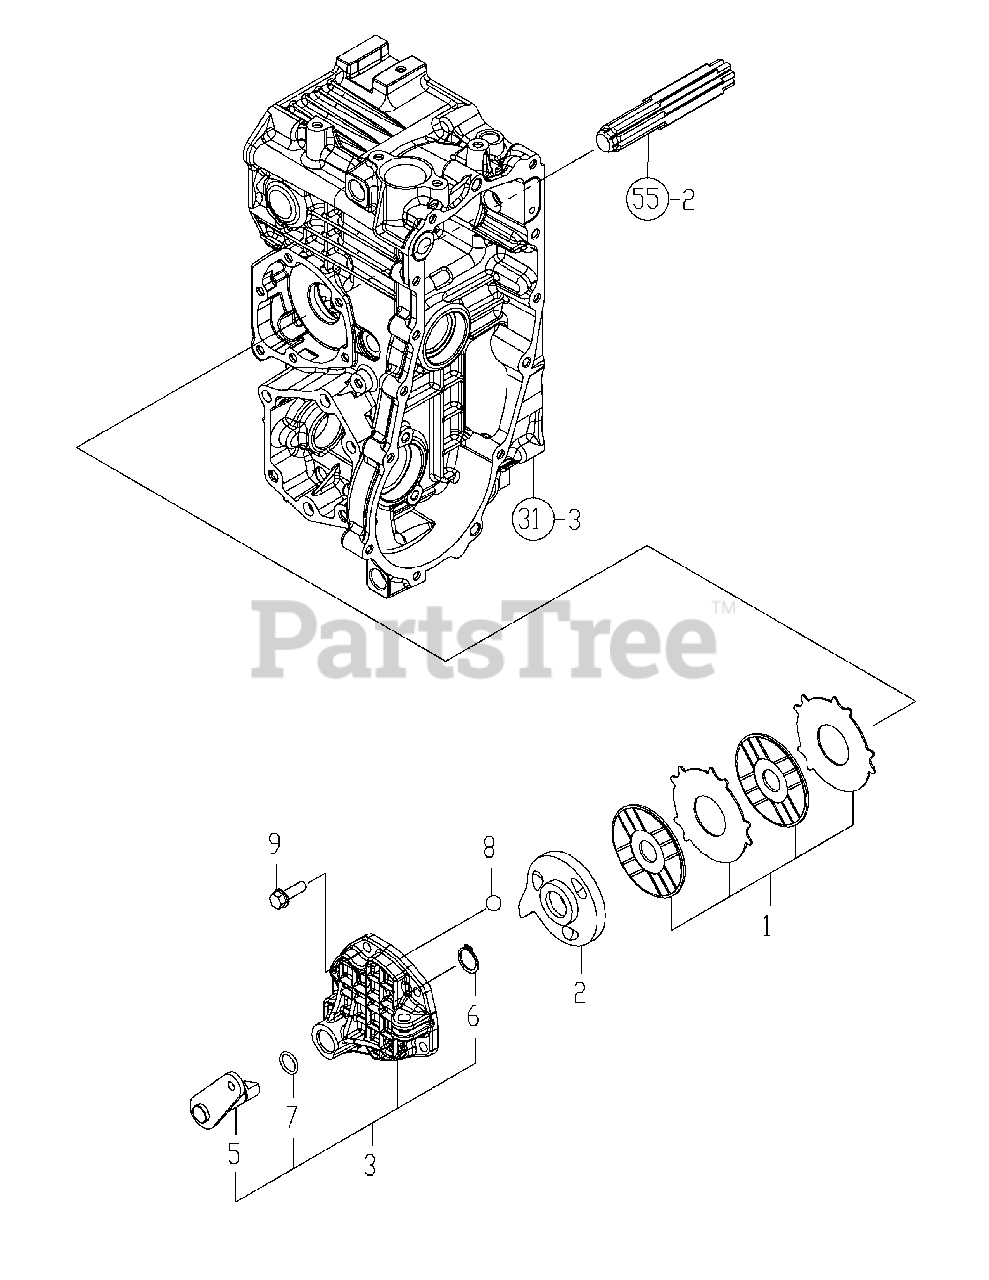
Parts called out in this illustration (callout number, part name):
1	PLATE KIT, BRAKE
3	CAM KIT, BRAKE
5	SHAFT ASSY, LEVER
7	PACKING, P 16.0
